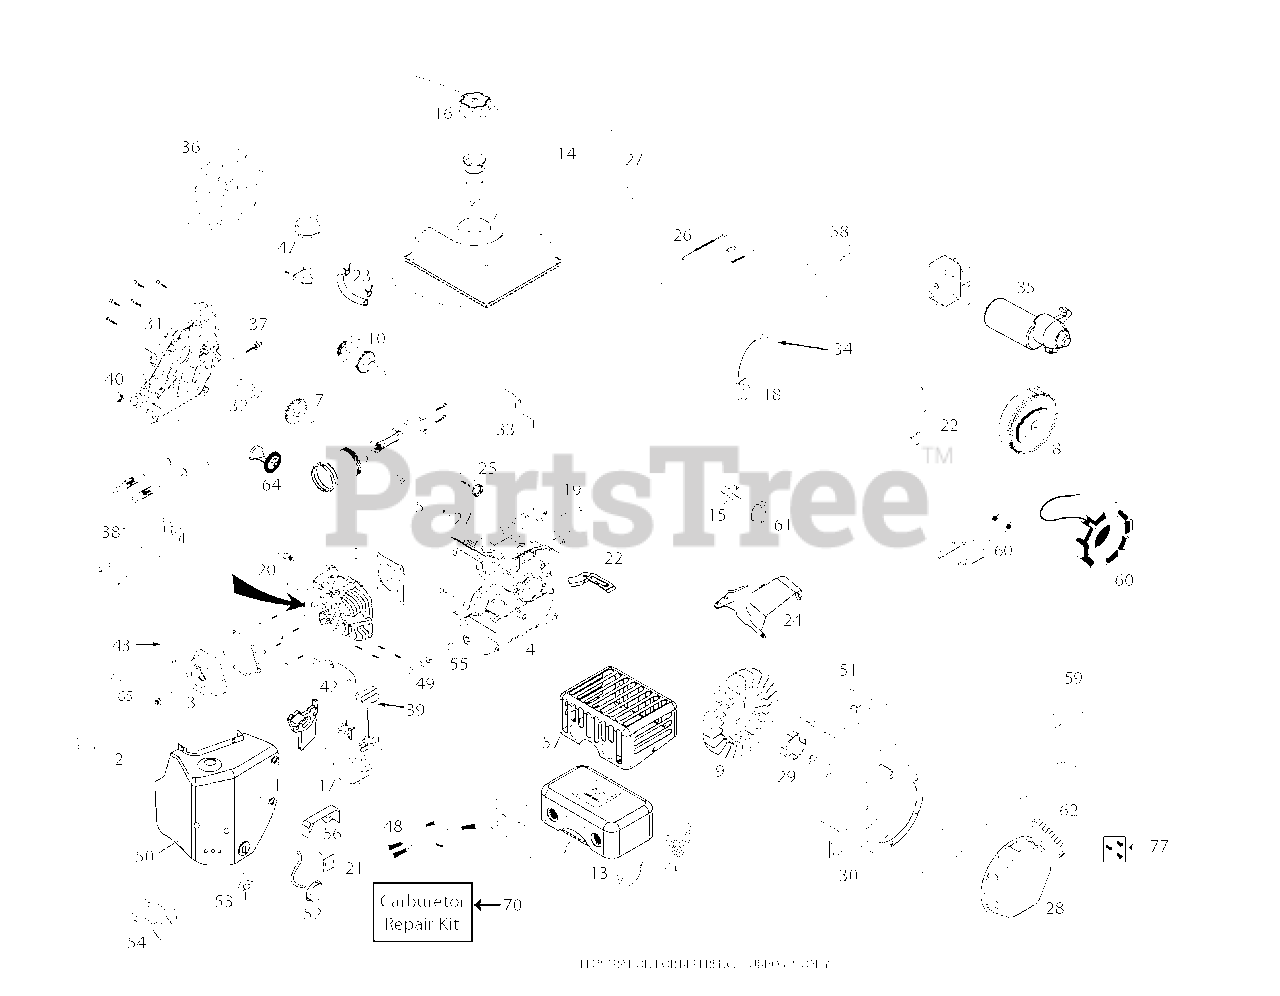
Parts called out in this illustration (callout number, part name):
1	CYLINDER.HEAD.ASSY(SK2911000)
2	PUSH ROD TAPPET KIT
3	VALVE.COVER.LCT.414CC.
4	CYLINDER ASSY SNOW
5	PISTON.AND.ROD.ASSY(SK2911400)
7	CAMSHAFT.LCT.291CC
8	FLYWHEEL.EL.ST.SKSNO2401.1
9	FLYWHEEL.FAN
10	CRANKSHAFT.KEYED.SNOW.291CC.LC
13	MUFFLER.ASSY.SNOW(SKSN4200)
14	FUEL TANK ASSY - SNOW (291CC)
15	FUEL.PETCOCK.SNOW(SKSN4900)
16	FUEL.TANK.CAP.SNOW(SKSN4301)
17	CARBURETOR.ASSY.SNOW(SKSN2302)
18	IGNITION COIL ASSY
19	CDI.BOX.ASSY.SNOW(SKSN4404)
20	SPARK.PLUG(SK2911550)
21	ON/OFF.SWITCH.SNOW(SKSN4403)
22	SHIELD.U/FYWHL.CHARG(SKSN4604)
23	KIT.FUEL.HOSE.208CC.SING/STAGE
24	TOP.SHIELD.LCT.
25	GOVERNOR.GEAR.ASSY(SK2912900)
26	GOVERNOR.ARM.ASSY.(SKSN2502)
27	GOVERNOR.SHAFT.(SK2913100)
28	RECOIL.START.ASSY.(SKSN2600)
29	STARTER.CUP.SMALLSNOW(SKSN2601
30	HOUSING.BLOWER.ASM
31	CRANKCASE.COVER.ASY(SK2913600)
32	OIL.SEAL.KIT(SK2913900)
33	ELECTRIC.START.BRKT(SKSN4405)
34	SPARK.PLUG.BOOT.SNW,SKSN4691.1
35	ELECTRIC.START.ASSY(SKSN2400)
36	ENGINE.GASKET.KIT(SK2914300)
37	DIPSTK.OIL.BLK.LCTSK4143711.1
38	ROCKER ARM KIT
39	CHOKE.KNOW.SNOW(SKSN4500)
40	NONREMVABLE.OIL.PLUG(SK4143715
42	CDI.BOX.BRKT.SNOW(SKSN4402)
43	TUBE.BREATHER.LCT.219CC/414CC
47	HIGHOIL.FILL.ASSY.KIT(SKSN4911
48	WIRE.HARNESS(SKSN4406)
49	OIL.DRAIN.PLUG
50	HEATER.BOX.ASSY.SNOW(SKSN2100)
51	SHIELD.CYLINDER.SNOW(SK4141010
52	PRIMER.BULB.ASSY(SKSN4304)
53	KEY.SWITCH.ASSY.SNOW(SKSN4401)
54	KEY SET(2 KEYS) SKSN0407.1
55	EXTENDED OIL DRAIN TUBE
56	SHIELD.VAPOR(SKSN4606)
57	SHIELD.MUFFLER.
58	GOVERNOR.LINK.SHIELD(SKSN2501)
59	FUEL.TANK.SKIRT(SKSN2101)
60	ALTERN.60WATT.SKSN2402.1
61	FUEL KNOB-SNOW
62	STARTER.GRIP.SNOW(SKSN2603.1)
65	TAPPET KIT.LCT.SK2911005.1
70	Carburetor Repair Kit, 291CC/4
77	BOLT.KIT.RECOIL.LCT.ALL.ENGINE
